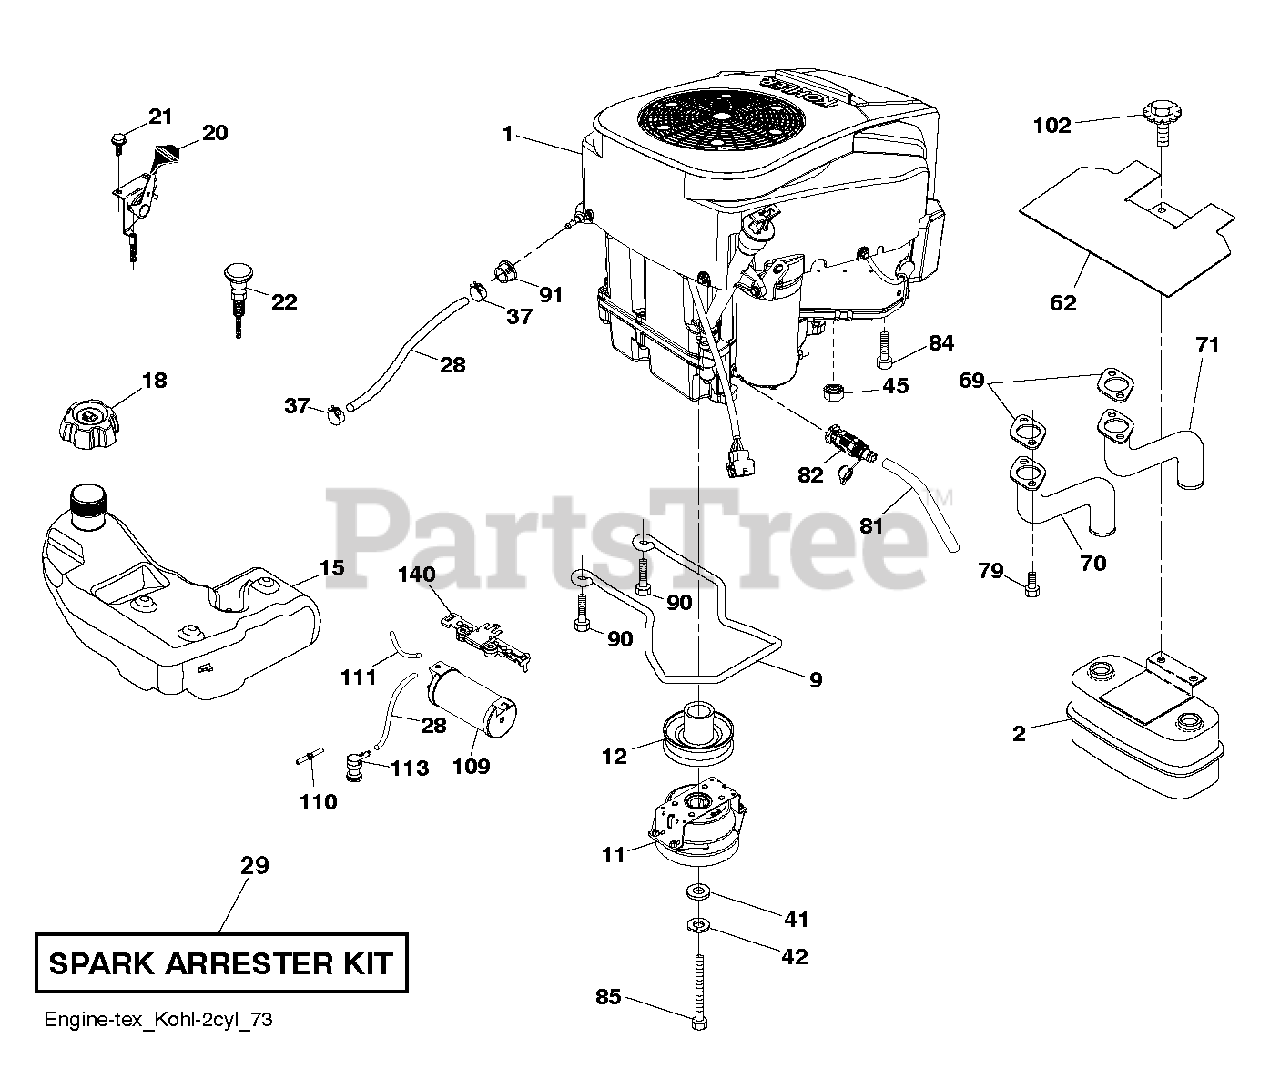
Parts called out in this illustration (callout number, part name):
2	Muffler Assembly, Twin MN
9	KEEPER.BELT.ENG.4.25"2.BLT.431
11	CLUTCH.OGURA.5.0PD.GT1.5A-EH01
12	PULLEY ENGINE
15	FOAM PLASTIC TANK.ASM.FUEL.4 G
18	CAP ASSY FUEL 3" GRAY
20	THROTTLE CONTROL
21	SCREW.#10 X 0.750.BOS
22	CONTROL.CHOKE.ERGO.PUSH-IN.BLA
28	Fuel Hose, 1/4" Low Perm
29	KIT.SPARK ARRESTOR 794945 B&S
37	HOSE CLAMP
42	WASHER 7/16 LOCK
45	NUT
62	SHIELD.HEAT.MUFFLER
69	GASKET.EXHAUST.KOHL.CV18-CV26
70	PIPE.EXHAUST.LH.CV18/20
71	PIPE.EXHAUST.RH.CV18/20
79	SCREW.SOCKET HD.5/16-1
81	TUBE, DRAIN OIL ASM.
82	VALUE.OIL.DRAIN
84	SCREW 3/8-16X1
85	BOLT.HEX.7/16-20X3.GR5.YELLOW
90	SCREW 3/8-16X1
91	BUSHING.1.375OD
102	SCREW
109	CANISTER CARB, FLEX TECH, 6.3
110	VALVE.ASM.ANTI-SLOSH
111	RP PURGE LINE
113	VALVE.SLANT.CARTRDG.90 DEG.TEX
140	BRACKET BRACKET, CARBON CAN, F
